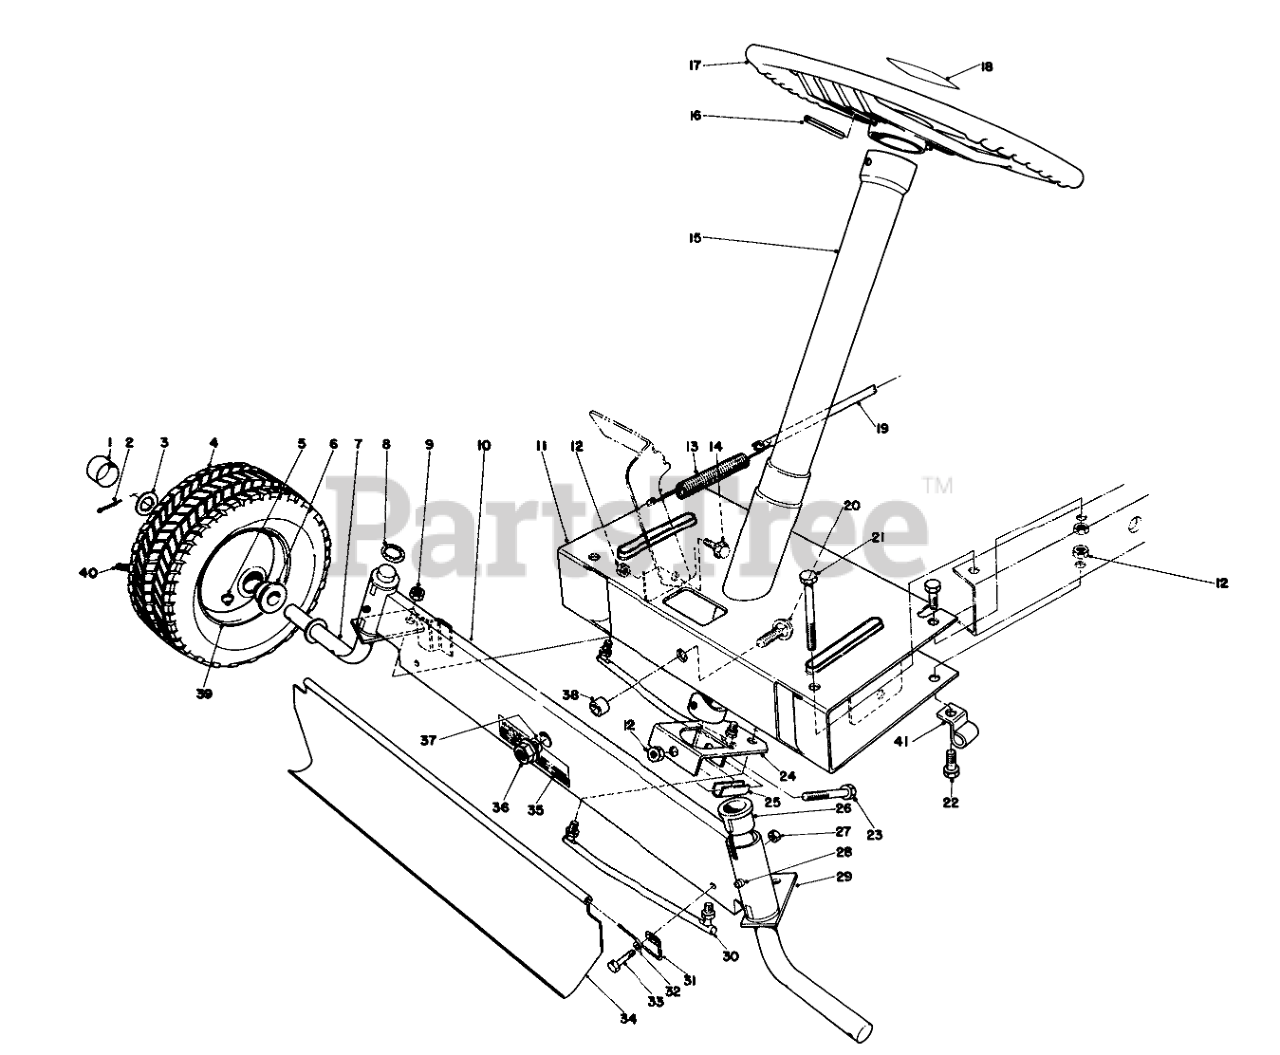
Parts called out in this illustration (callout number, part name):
1	Hub Cap
2	PIN-COTTER
3	WASHER-FLAT
4	Tire Turf King
5	FITTING-GREASE
6	BUSHING
7	SPINDLE WA RH
8	RING-RETAINING
9	NUT-LOCK NI
10	Front Axle
11	Front Frame
12	NUT-LOCK, CONE
13	BRAKE TENSION SPRG O
14	SCREW-SHOULDER
15	Steering Tube
16	PIN-ROLL
17	Steering Wheel
18	Decal
19	Brake Rod
20	SCREW-CARR
21	SCREW-HH
22	SCREW-HH
23	SCREW-HH
24	Lever Steering
25	Spacer-Steering Tube
26	BUSHING
27	NUT-LOCK, CONE
28	GREASE FITTING
29	Spindle L.H.
30	TIE ROD ASM
31	Hanger-Safety Shield
32	WASHER-FLAT
33	SCREW-HH
34	Safety Shield
35	Decal-Warning
36	NUT-HF
37	WASHER-THRUST
38	FRONT AXLE SPACER
40	STEM-VALVE
41	Bracket-Guard Support
